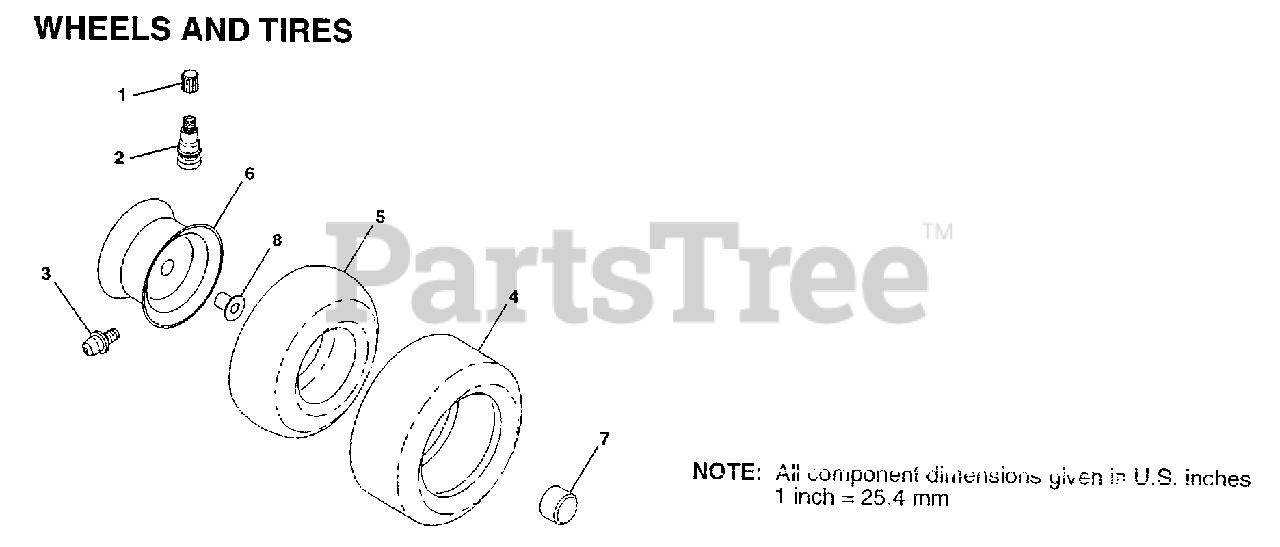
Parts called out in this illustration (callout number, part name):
1	VALVE CAP
2	VALVE STEM LT
3	FITTING LT
5	TUBE.5.3/4.5/6
5	TUBE.23X8/10-12
7	HUB CAP
8	"FLANGE, BEARING"
